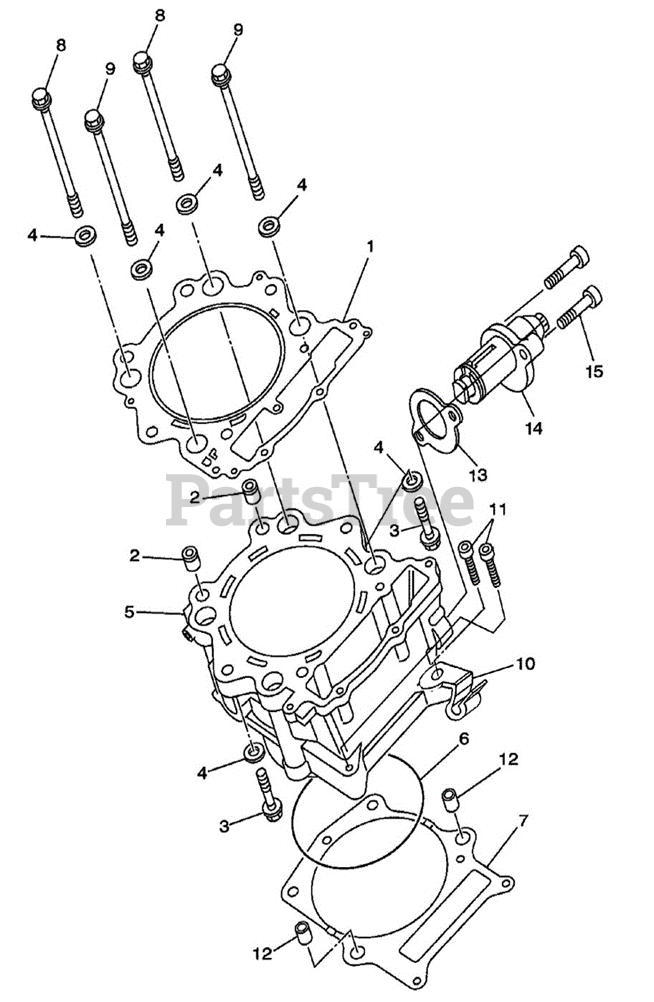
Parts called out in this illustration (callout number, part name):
1	CYLINDER HEAD GASKET
2	DOWEL PIN 12X16
3	CYLINDER BOLT M9X1.25X39
4	WASHER 10X19X2
5	CYLINDER BODY ASSEMBLY
6	O-RING 105.7X2.8
7	CYLINDER BODY GASKET
8	CYLINDER BOLT M10X1.25X121
9	CYLINDER BOLT M10X1.25X128
10	PIPE CLAMP
11	HEX HEAD CAP SCREW M6X40
12	DOWEL PIN 14X16
13	TENSIONER GASKET
14	TENSIONER
15	HEX HEAD CAP SCREWM6X115
